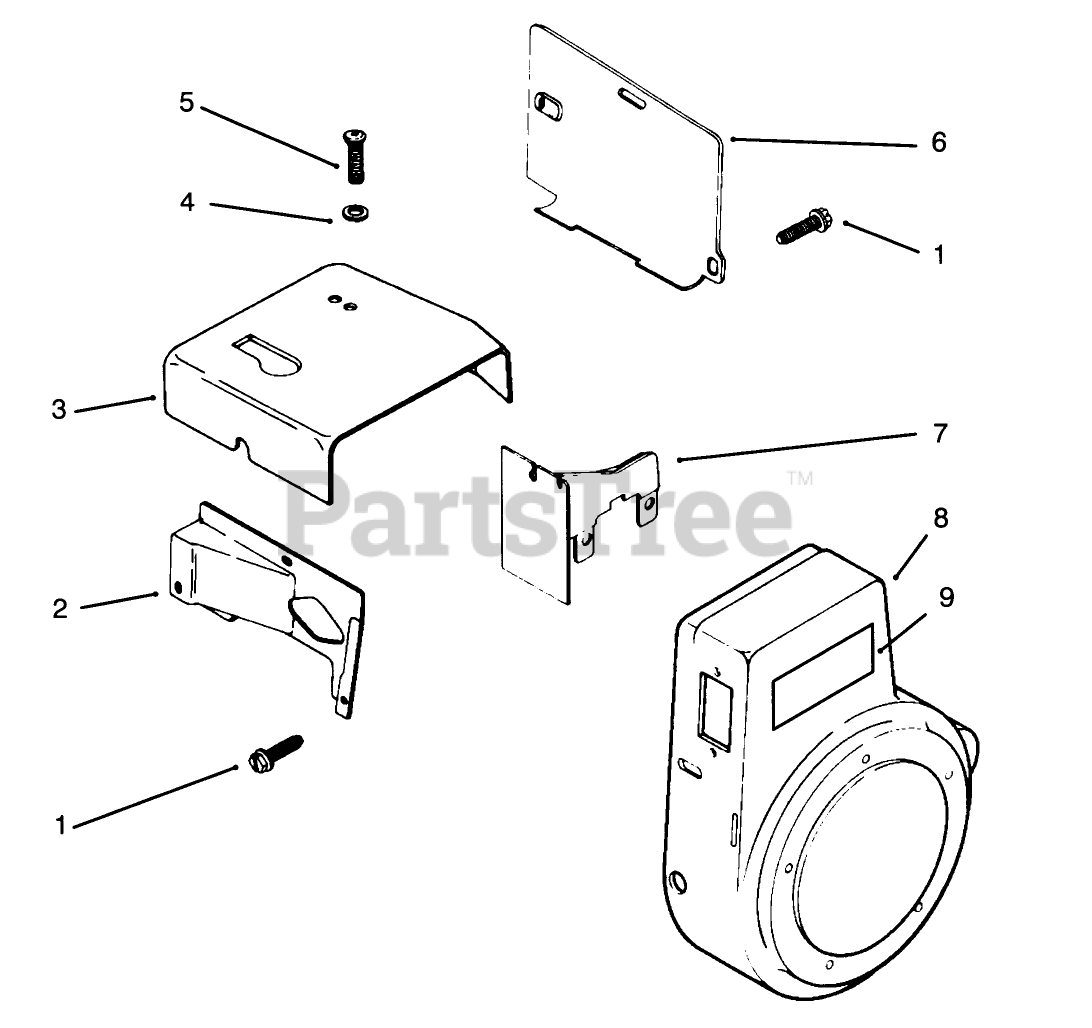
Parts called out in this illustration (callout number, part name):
1	KOHLER 52-086-11
2	KOHLER 47-063-06
3	KOHLER 45-063-08
4	KOHLER X-25-53
5	KOHLER 47-086-08
6	KOHLER 47-063-10
7	KOHLER 47-063-07
8	KOHLER 47-027-42
9	VNDR #47-113-36
